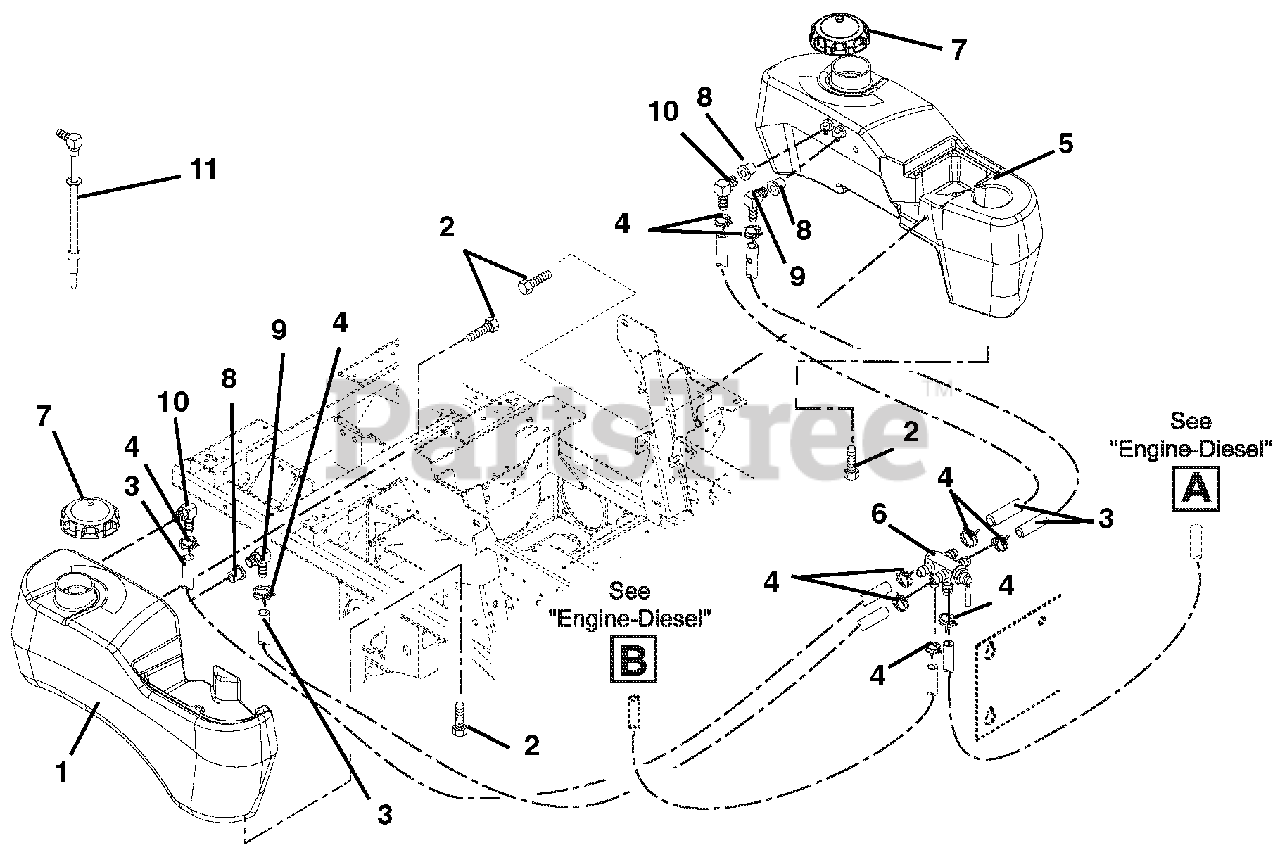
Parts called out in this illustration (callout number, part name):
1	TANK, GAS RH (200 W/RETURN)
2	BOLT, SEMS .31-18 X .62
3	HOSE,5/16 ID
4	CLAMP, HOSE WIRE .520/.550
5	TANK, FUEL-LH(W/RTN)W/O HOSE
6	VALVE, FUEL
7	CAP, FUEL
8	GROMMET, DAPCO VITON #12240
9	FITTING, TANK ELBOW .31 HOSE
10	FITTING, TANK (5/16 ELBOW)
11	26" FUEL LINE KIT-DIESEL & EFI
